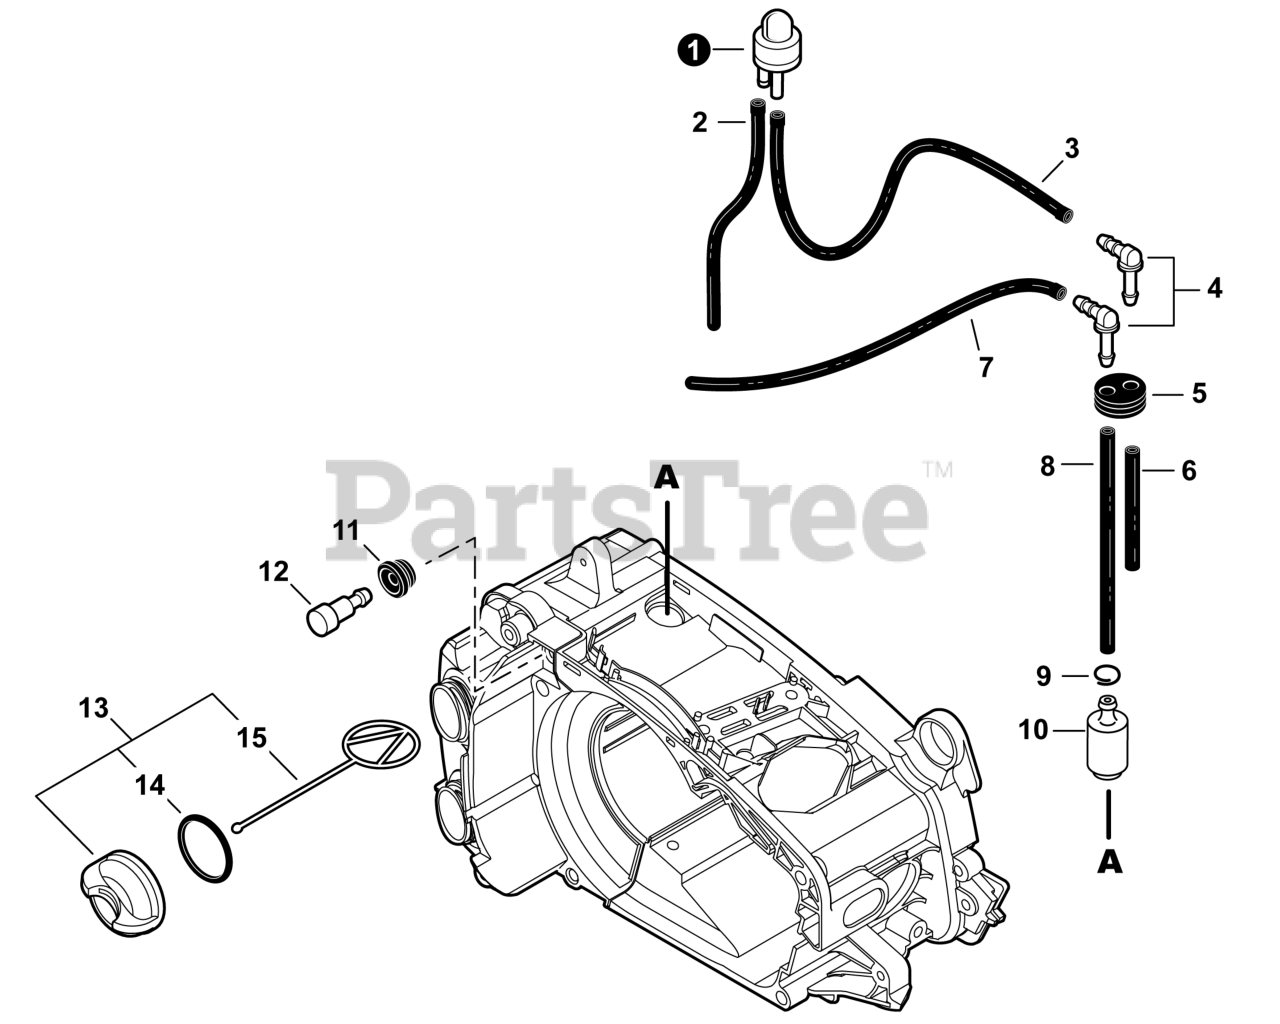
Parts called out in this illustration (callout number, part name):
1	BULB, PURGE
2	PIPE 2.4x5x180 - BLACK
3	PIPE 2.4x5x400 - BLACK
4	CONNECTOR, PIPE
5	GROMMET, FUEL
6	PIPE 2.4x5x15 - BLACK
7	PIPE 3x5x265 - BLACK
8	PIPE 3x5x140 - BLACK
10	FILTER, FUEL
11	GROMMET, FUEL
12	VENT ASSY
13	CAP ASSY, FUEL
15	CONNECTOR, CAP L= 60 MM
